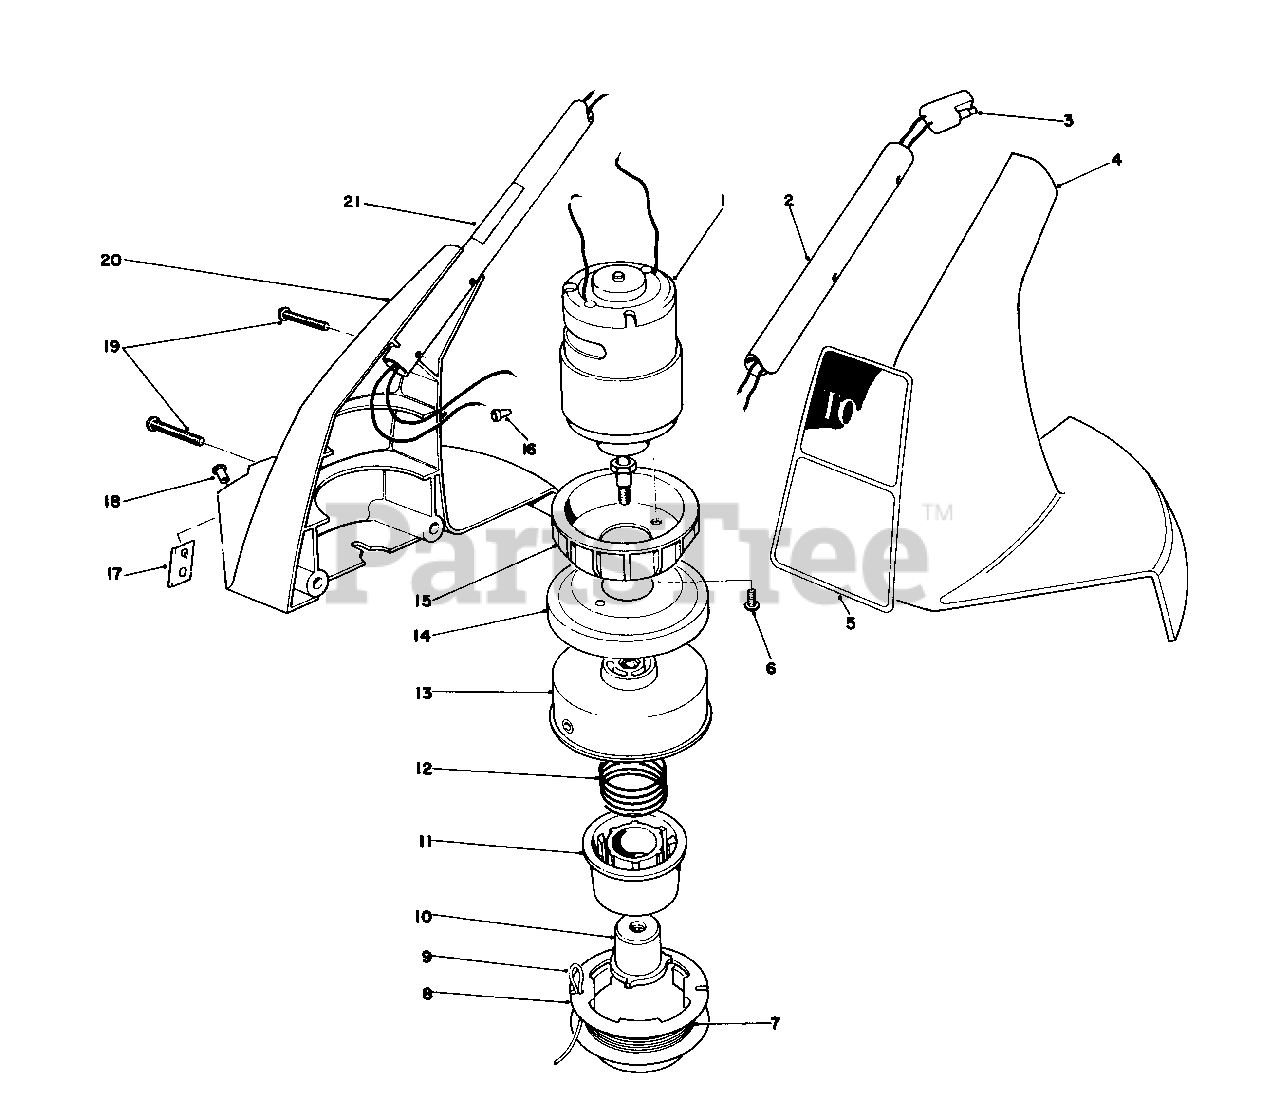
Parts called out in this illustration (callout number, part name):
3	Lower Wiring Harness
4	Left Hand Housing
5	Decal-CL-710
7	12 ft. .050 dia. Cutting Line Prewound on Spool
8	Empty Spool
9	30 ft. of .050 dia. Cutting Line in Coil
12	Spring
13	Drum w/Eyelet
14	Drum Cup
15	Heat Sink Casting
16	Wire Connector
17	Knife Blade
18	Rivet
20	R.H. Motor Housing (Incl. Ref. #17 & 18)
21	Decal-Serial Replacement
